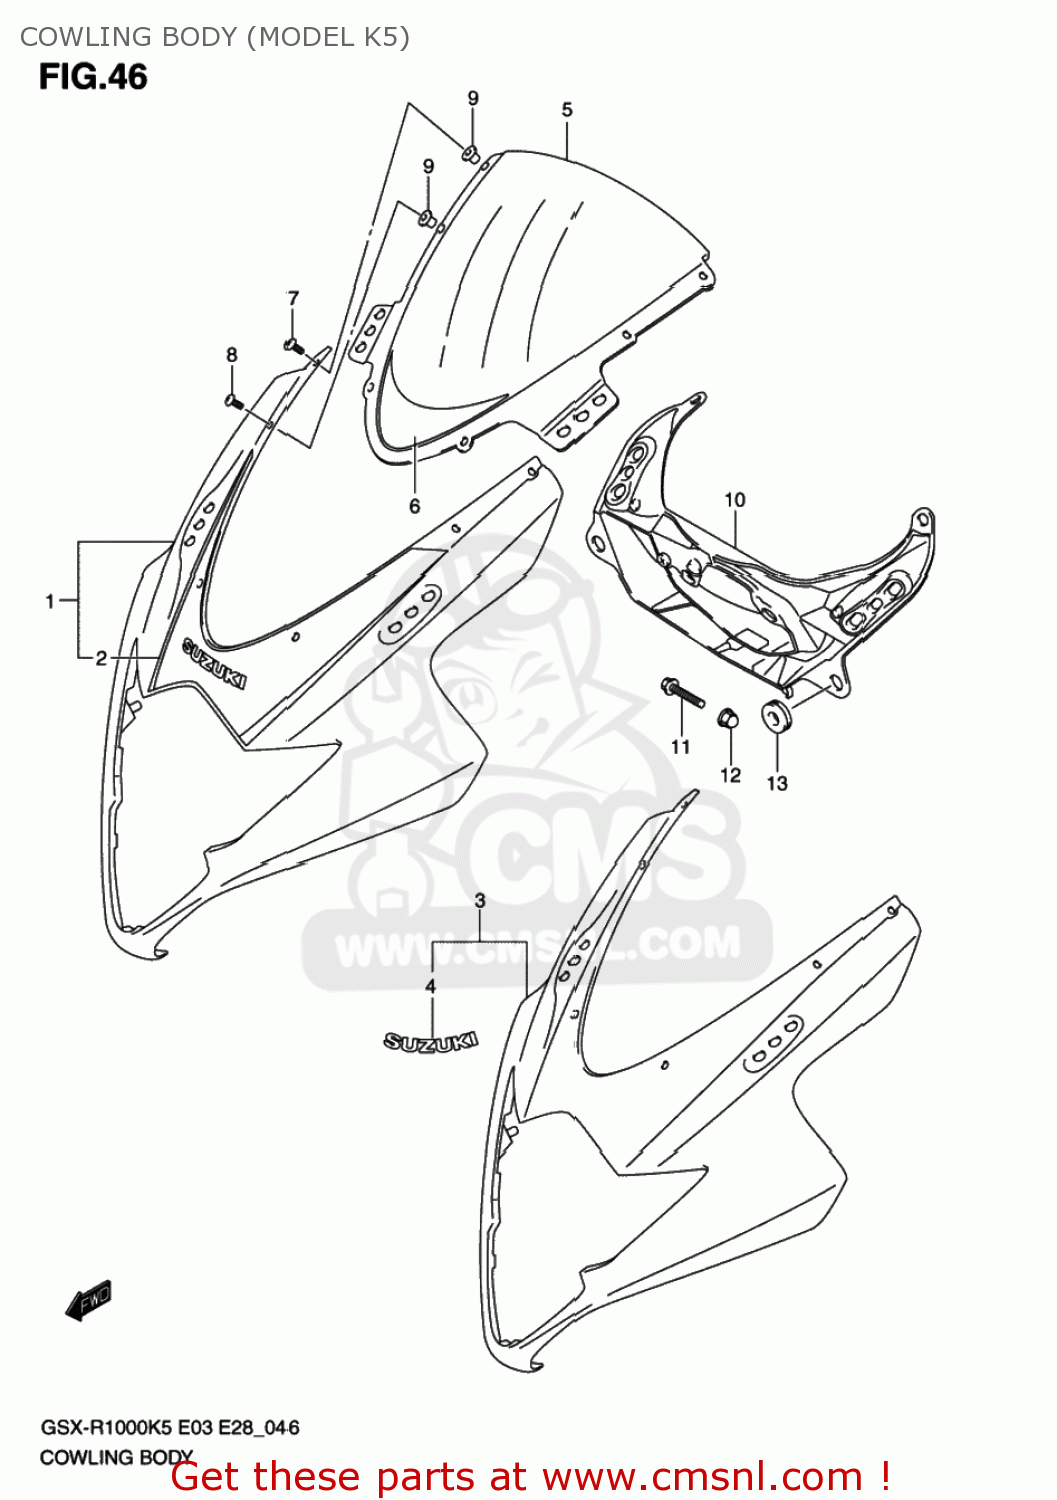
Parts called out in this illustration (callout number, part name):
1	BODY,COWLING
2	TAPE,BODY COWL
3	BODY,COWLING
4	EMBLEM,SUZUKI
5	WINDSCREEN
6	TAPE,SCREEN
7	SCREW(5X15)
8	SCREW(5X18)
9	NUT
10	BRACE,COWLING
11	BOLT
12	NUT
13	CUSHION
